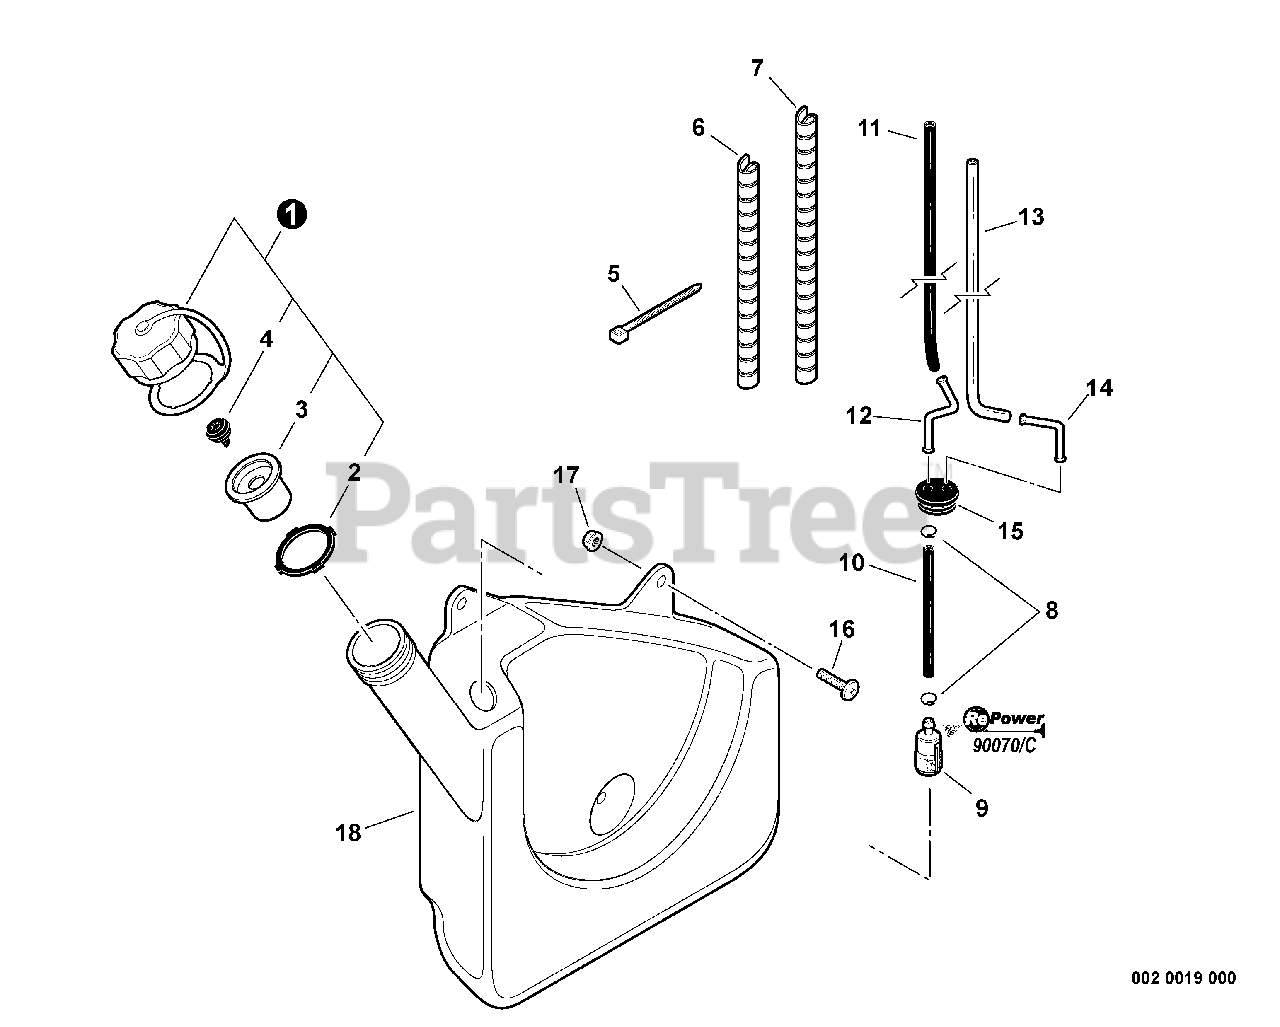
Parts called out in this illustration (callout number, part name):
1	CAP ASSY
2	GASKET, CAP
3	VENT HOLDER ASSY
5	TIE, CABLE - SMALL
6	WRAP, SPIRAL - 130mm
7	WRAP, SPIRAL
8	CLIP - 6.5
9	FILTER, FUEL
10	PIPE - 3X7X520 -- BLACK
11	PIPE - 3X6X280 -- BLACK
12	CONNECTOR, PIPE
13	PIPE - 2X4X480 -- CLEAR
14	CONNECTOR, PIPE
15	GROMMET
16	SCREW - 5X20
17	NUT - 5 -- FLANGE
18	TANK, FUEL
19	RePower TUNE-UP KIT
